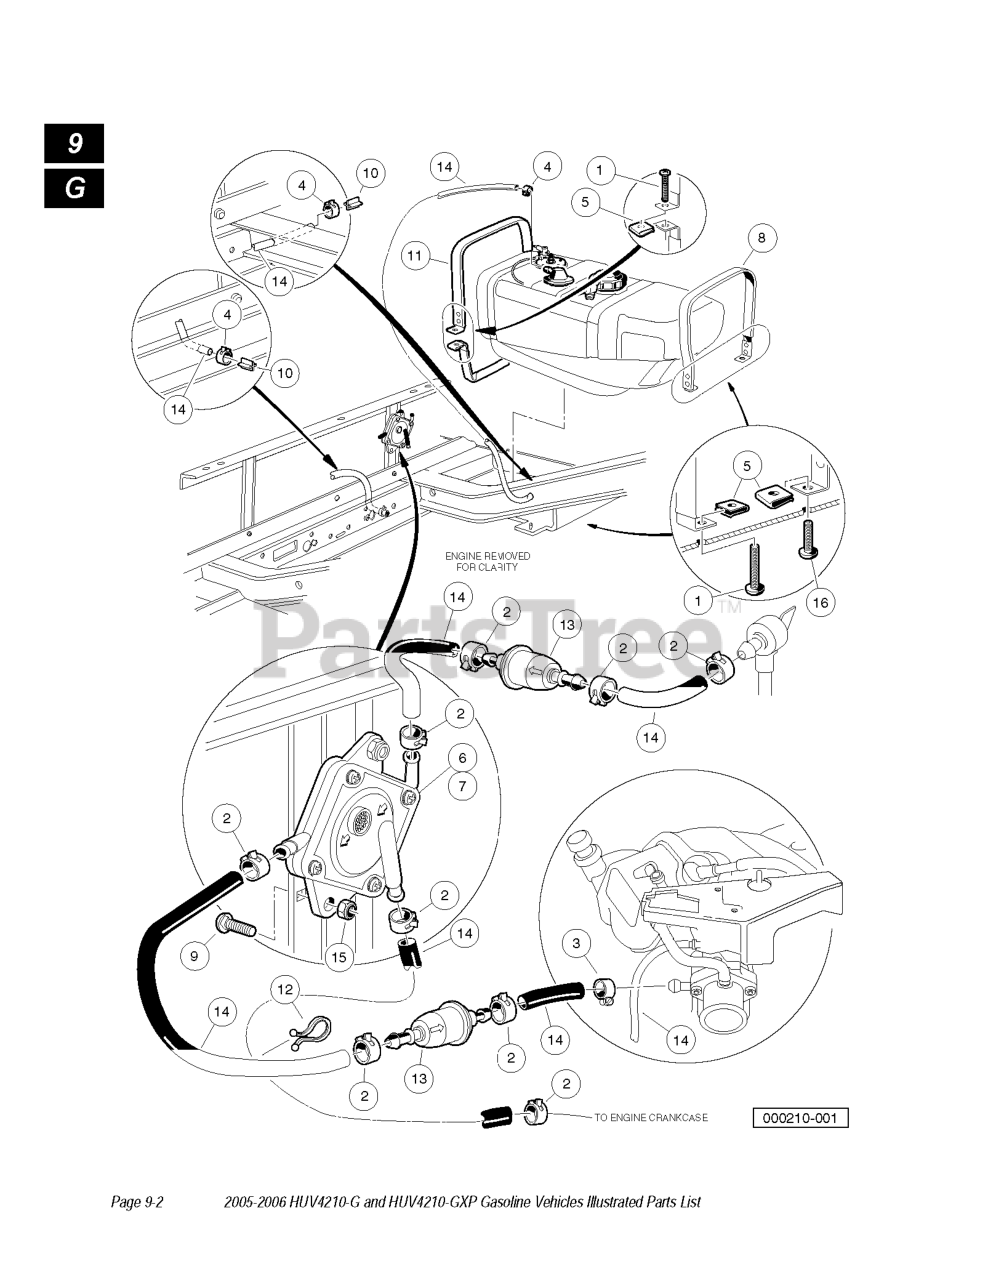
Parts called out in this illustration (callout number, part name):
1	SCREW PHL TRUSS
3	LAMP, 3/8" S.S HOSE
5	NUT, 1/4-20 SPEED
6	PUMP, IMPULSE FUEL
7	SQ IMPULSE PUMP REBUILD KIT
8	FUEL STRAP ASSEMBLY REAR
9	BOLT, 1/4-20 X 1.0 RD HD SQ NK
11	FUEL STRAP ASSY, FRONT
12	CLAMP, PLASTIC TIE
13	FILTER FUEL 30 MICRON
14	HOSE, FUEL, 1/4SAEJ1737 BULK
15	LOCKNUT, 1/4-20 NYLON INSERT
16	SCREW 1/4-20 X .75
